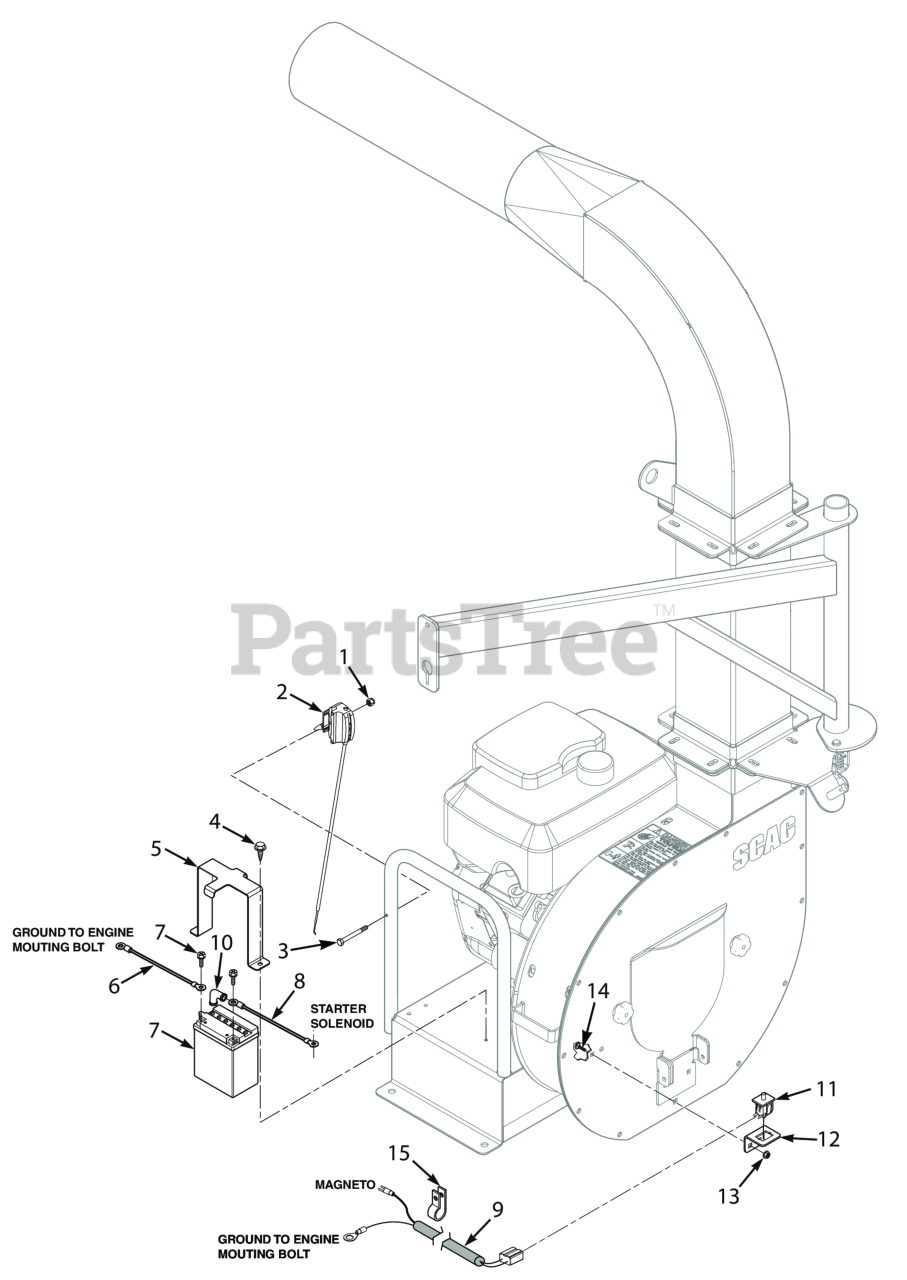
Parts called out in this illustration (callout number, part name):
1	HEX, NUT, ELASTIC STOP LOCK, 1/4-20
2	Throttle Control
3	Bolt, 1/4-20 x 2-1/2"
4	Screw, 1/4-20 x .625 Self Tap
5	Bracket, Battery
6	Battery Cable, 18" Black (Kohler)
7	Battery (not available through Scag)
8	Battery Cable, Red 9" (Briggs & Stratton)
9	Wire Harness, Safety Switch
10	RUBBER BOOT
11	SWITCH, NEUTRAL INTERLOCK
12	Bracket, Brake Switch
13	Nut, Serrated Flange 5/16-18 (Right Front Engine Mounting, Briggs and Kohler Only)
14	Bolt, Carriage 5/16-18 x 3/4"
15	Wire Loom
